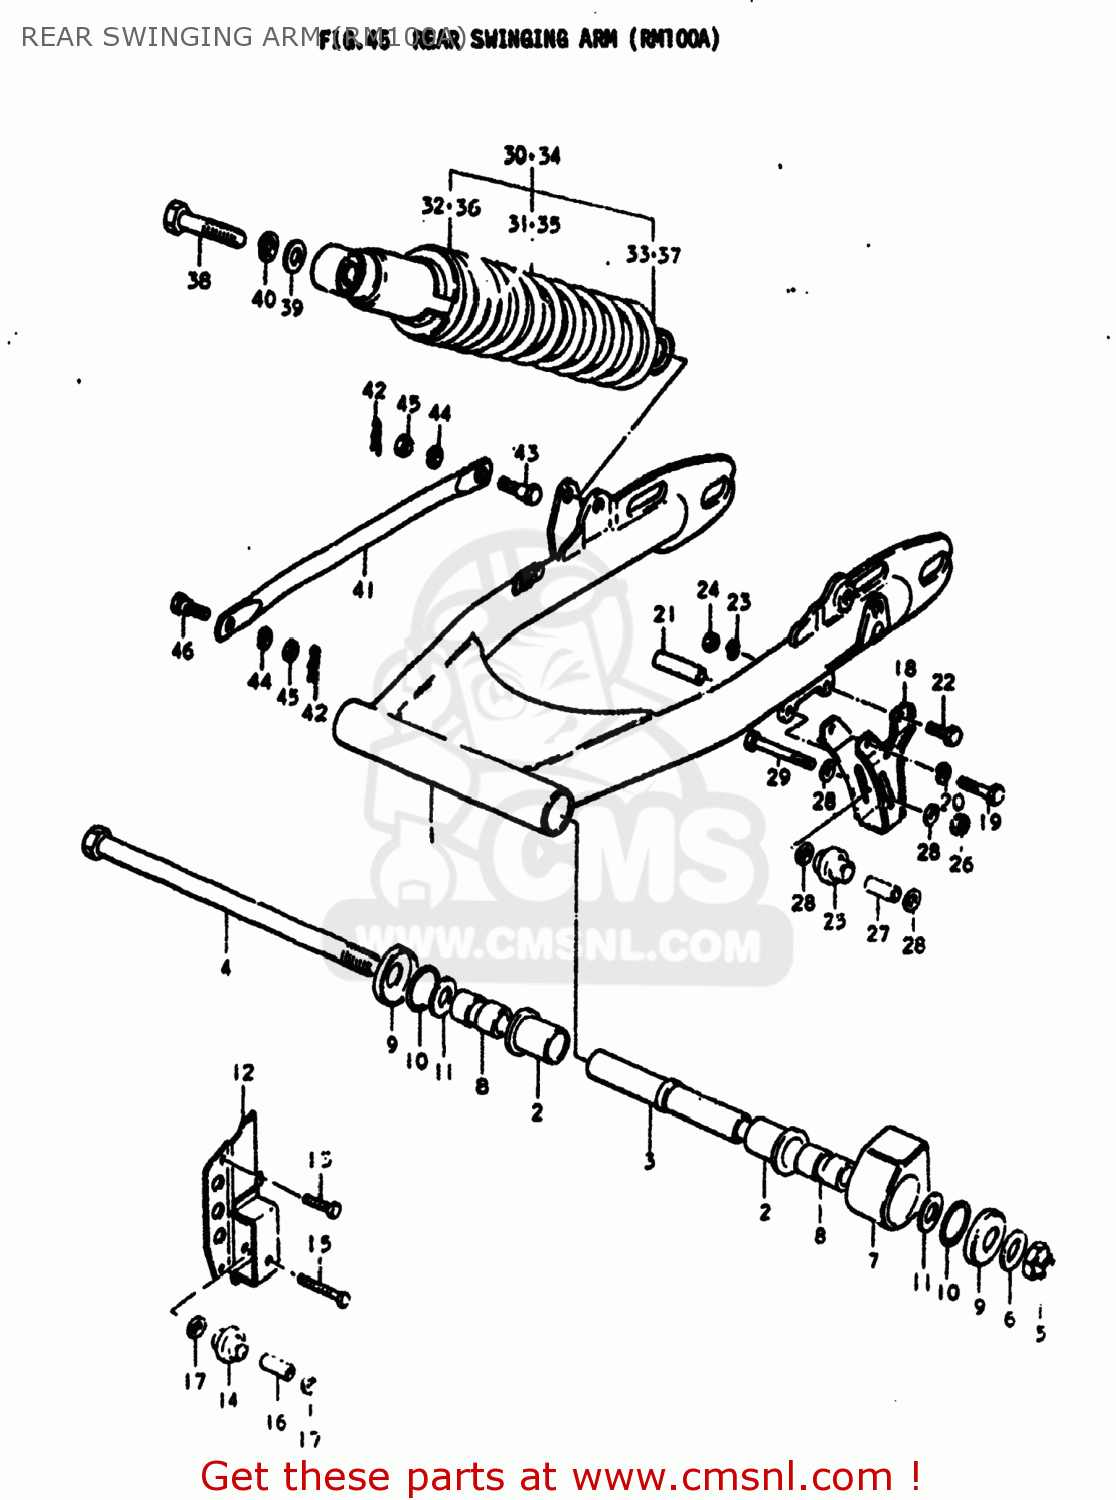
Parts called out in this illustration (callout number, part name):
1	SWING ARM ASSEMBLY,REAR
2	BUSHING
3	SPACER,SWING ARM,CENTER
4	SHAFT,PIVOT
5	NUT
6	WASHER
7	BUFFER,CHAIN TOUCH DEFENSE
8	SPACER,RR SWGARM PIVOT
9	COVER,SWGARM BUSH DUST SEAL
10	O RING(D:2,ID:24.5)
11	WASHER(12.5X24X2.3)
12	PLATE,CHAIN FRONT GUIDE
13	BOLT
14	RUBBER,CHAIN GUARD
15	BOLT
16	SPACER(6.5X10.5X22.5)
17	WASHER (6.5X20X1.2)
18	GUIDE
19	BOLT
20	LOCK WASHER
21	SPACER
22	BOLT
23	LOCK WASHER
24	NUT
25	RUBBER,CHAIN GUARD
26	NUT (6MM)
27	SPACER(6.5X10.5X22.5)
28	WASHER
29	BOLT
30	ABSORBER ASSEMBLY,REAR SHOCK
31	SPRING
32	GUIDE,SPRING
34	ABSORBER ASSEMBLY,REAR SHOCK
35	SPRING
38	BOLT 10X40
39	WASHER
40	LOCK WASHER
41	TORQUE LINK,REAR
42	CLIP
43	BOLT(8X26.5)
44	LOCK WASHER
45	NUT
46	BOLT(8X22)
